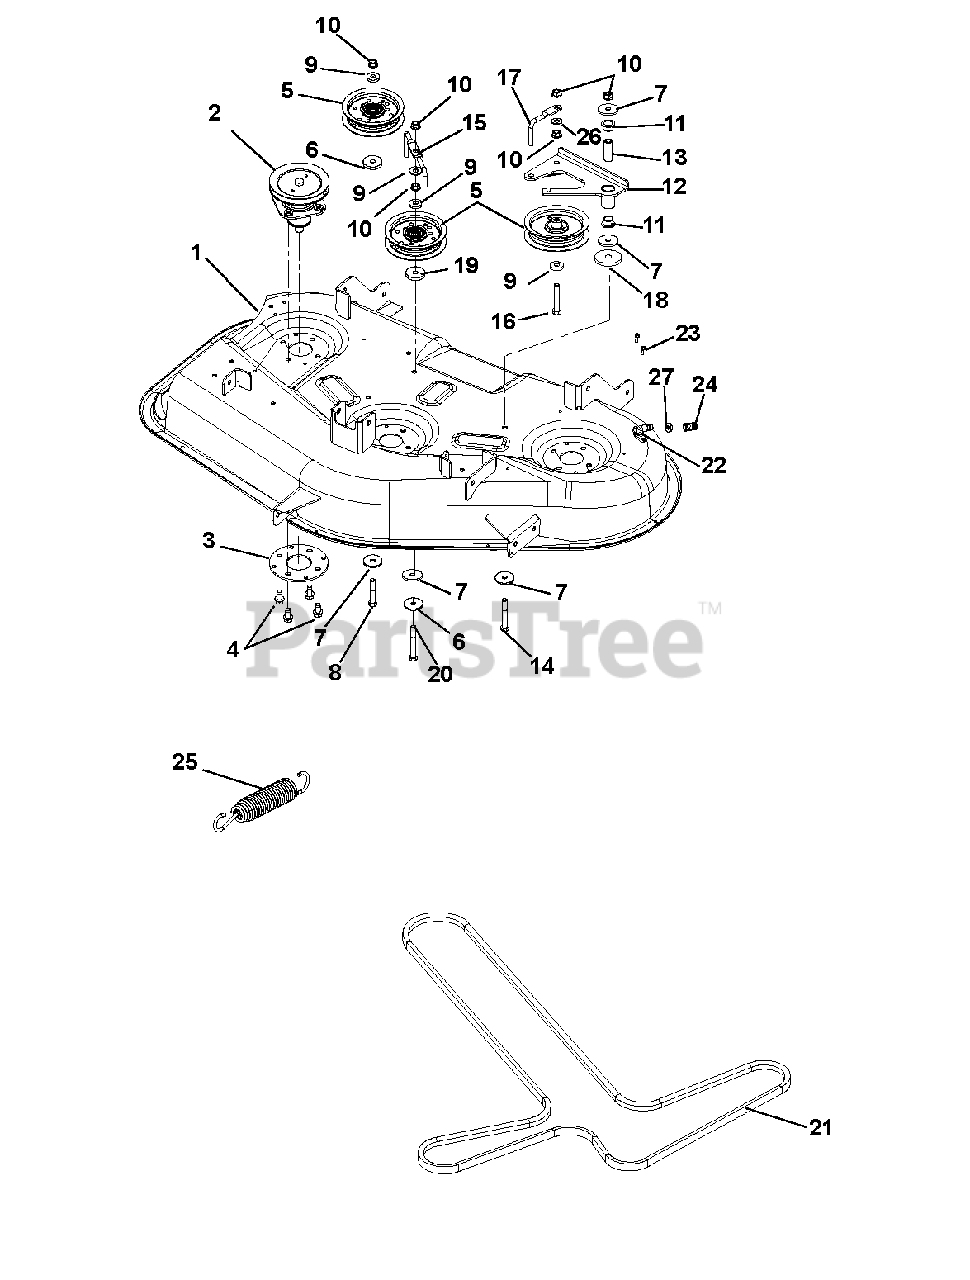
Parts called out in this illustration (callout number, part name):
1	Kit, Ariens 42" Deck with Decals
2	Assembly, Spindle
3	Plate, Spindle
4	Screw, Tapping .38-16 x .75 Hex Washer Head
5	Assembly, Idler 4"
6	Washer, Flat Steel .406 x 1.50 x .245
7	Washer, Flat Steel .380 x 1.50 x .125
8	Bolt, Hex .38-16 x 2.25
9	Washer, Flat Steel .406 x 1.00 x .188
10	Nut, Locking Top Flange .38-16
11	Bushing, Flange, .625 x .750 x .500 x 1.00
12	Idler Arm
13	Spacer, .375ID x .625 OD x 1.66
14	Bolt, Hex .38-16 x 3.00
15	Belt Finger
16	Bolt, Hex .38-16 x 2.25
17	Wireform Belt Finger
18	Washer, Flat Steel .469 x 2.00 x .25
19	Washer, Flat Steel .438 x 1.00 x .083
20	Bolt, Hex .38-16 x 2.75
21	V-Belt, 4L Wrapped
22	Assy, Washout Port W/O Ring
23	Screw, Tapping .25-20 x .62 Hex Washer Head Thread Rolling
24	Coupling, Quick Disconnect
25	Extension Spring .135 x .98 x 6.0
26	Washer, Flat Steel .406 x .812 x .065
27	O-Ring .362 X .103 X .568
